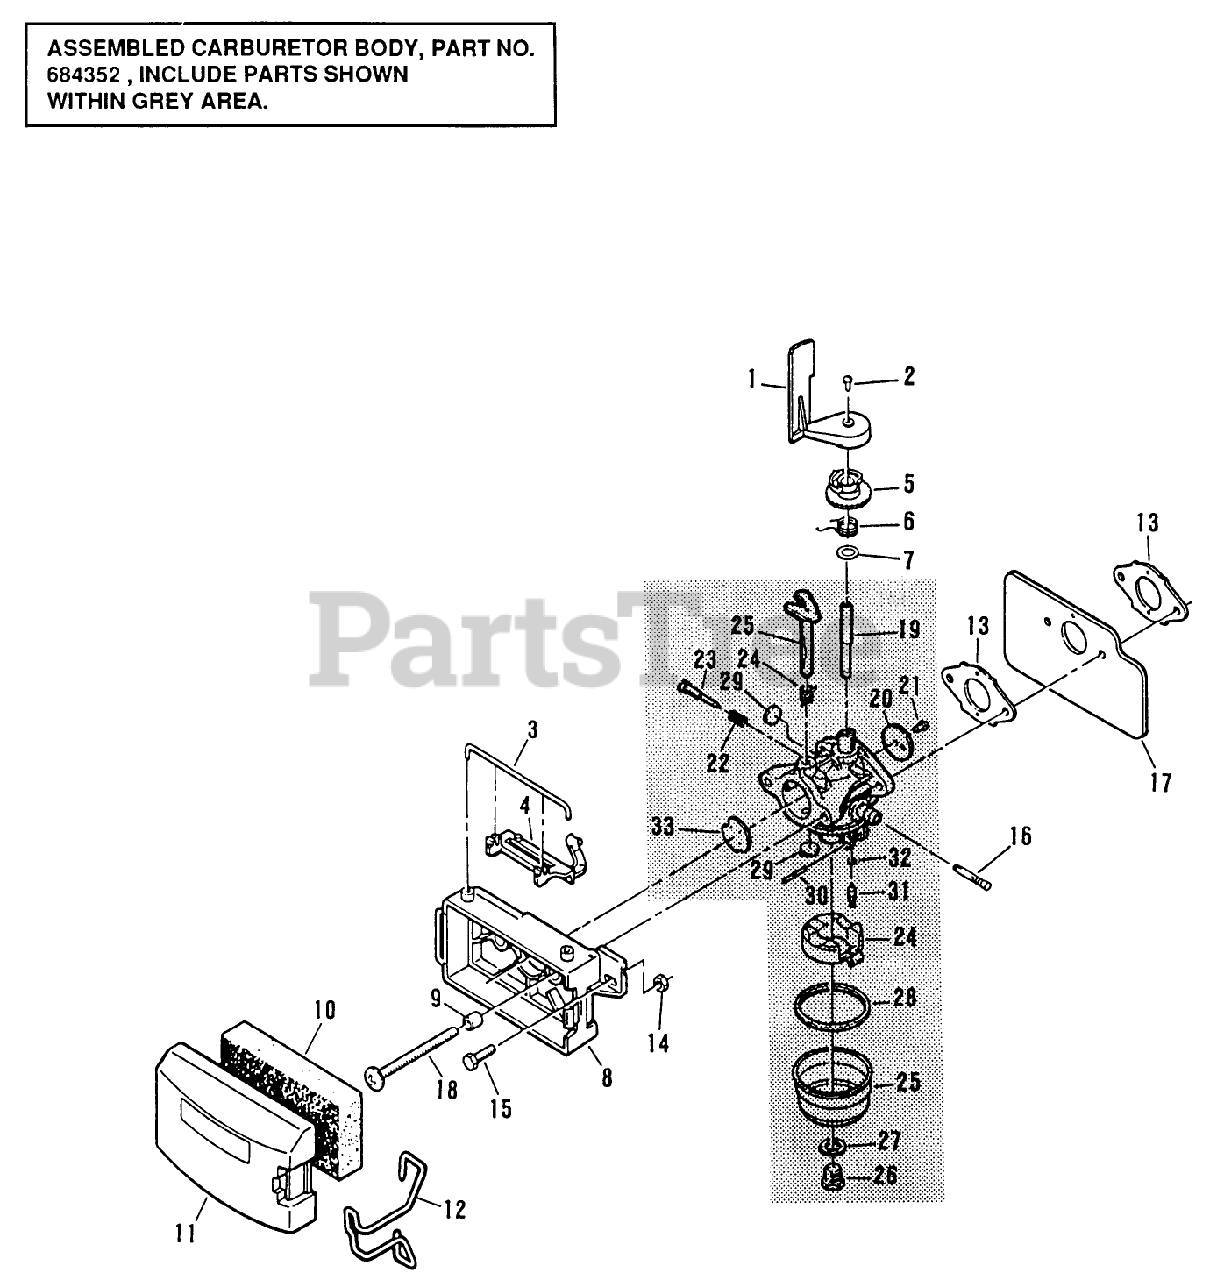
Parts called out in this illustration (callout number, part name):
1	AIR VANE F
2	SCREW F
3	RETAINER
5	COLLAR A/VAVE F
6	THROTTLE SPR E
7	WASHER VF
9	SPACER
12	RETAINER-COVER, FILTER
13	GASKET CARB S
15	SCREW
16	SCREEN FUEL PITTS
17	SHIELD, CARB F
18	SCREW
19	Throttle Shaft
20	Throttle Valve
21	Screw-Throttle Valve
22	Spring-Idle Needle
23	Idle Needle
25	Fuel Bowl
26	Screw-Bowl Retainer
27	Bowl Retainer Gasket
28	Fuel Bowl Gasket
29	Plug-Welch
30	Float Shaft
31	Inlet Needle Valve
32	Valve Seat
33	Choke Valve
34	Choke Return Spring
35	Choke Shaft
